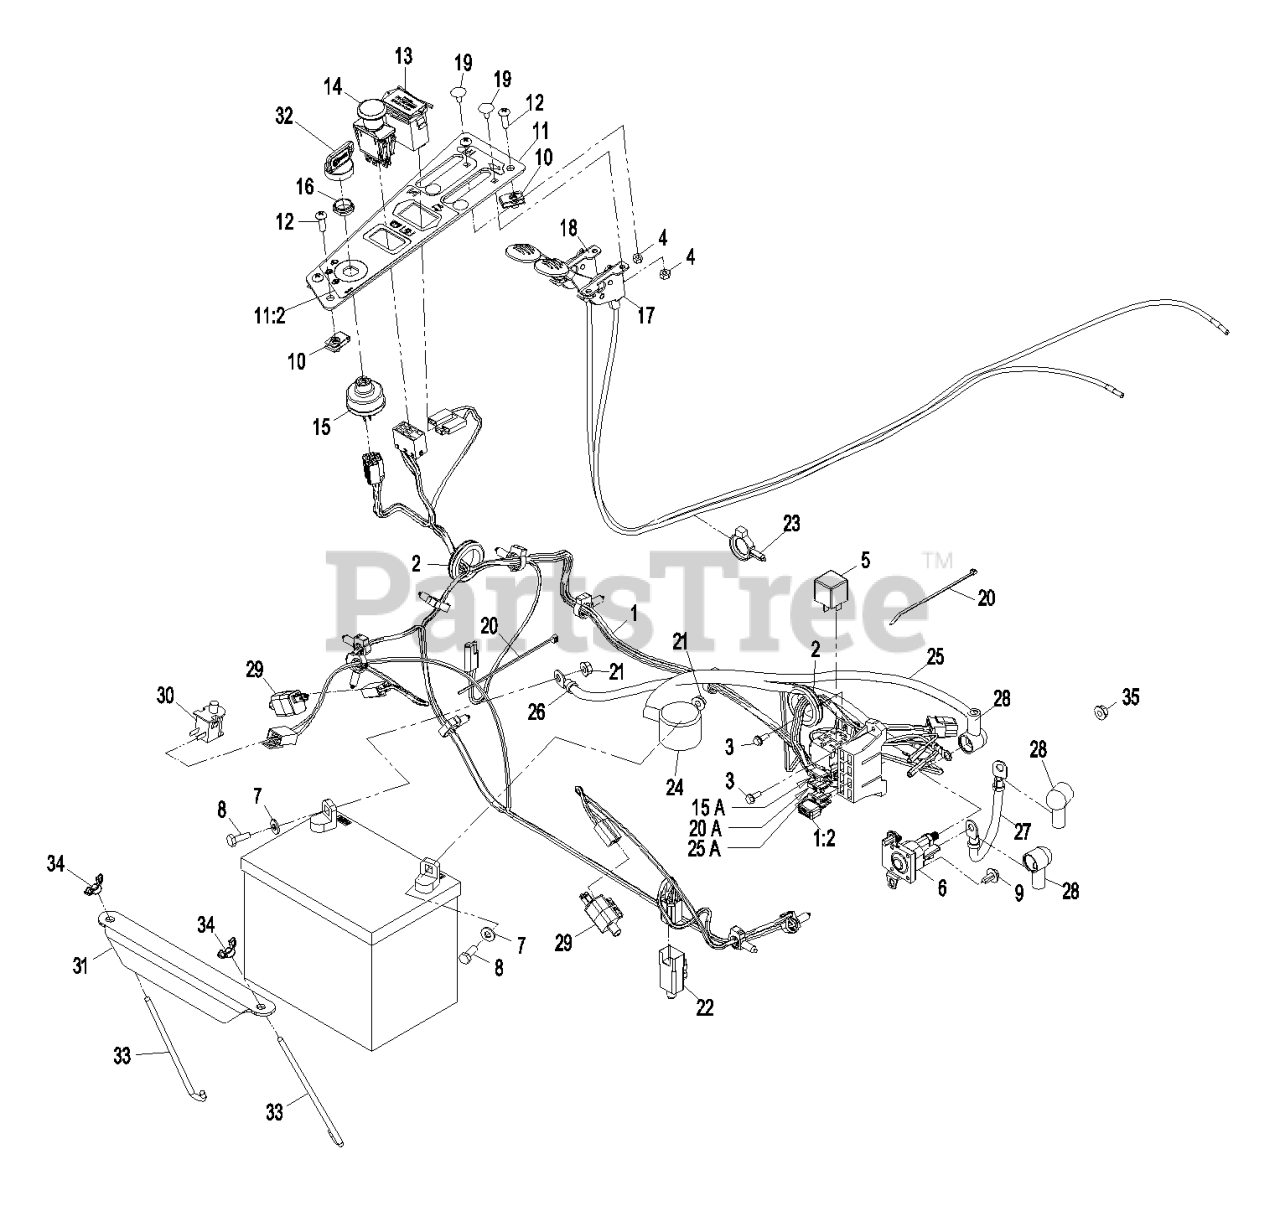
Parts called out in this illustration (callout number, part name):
1	HARNESS-WIRE
1:2	DIODE-TVS
2	GROMMET-RUBBER
3	SCREW-TAPTITE
4	NUT-LOCK, NI
5	RELAY
7	WASHER-FLAT
8	SCREW-HH
9	SCREW-HHFTF
10	Nut, Retainer-Panel 1/4-20
11	CONTROL PANEL ASM
11:2	DECAL-CONSOLE
12	SCREW-PRH
13	METER-HOUR
14	SWITCH-PTO
15	ASM,SWITCH W/NUT
16	NUT-SWITCH, IGNITION
17	CONTROL-THROTTLE
18	CONTROL,CHOKE
19	BOLT-CARR
20	TIE-CABLE
22	SWITCH-REVERSE
23	CLAMP-HOSE
24	INSULATOR-BATTERY
25	POSITIVE BATTERY CABLE AS
26	CABLE-GROUND, NEGATIVE
27	Cable, Starter +
28	INSULATOR-SOLENOID
30	SWITCH-BAIL
31	HOLDDOWN-BATTERY
32	KEY-IGNITION
33	BOLT-HOLDDOWN
34	WINGNUT
35	NUT-HF
